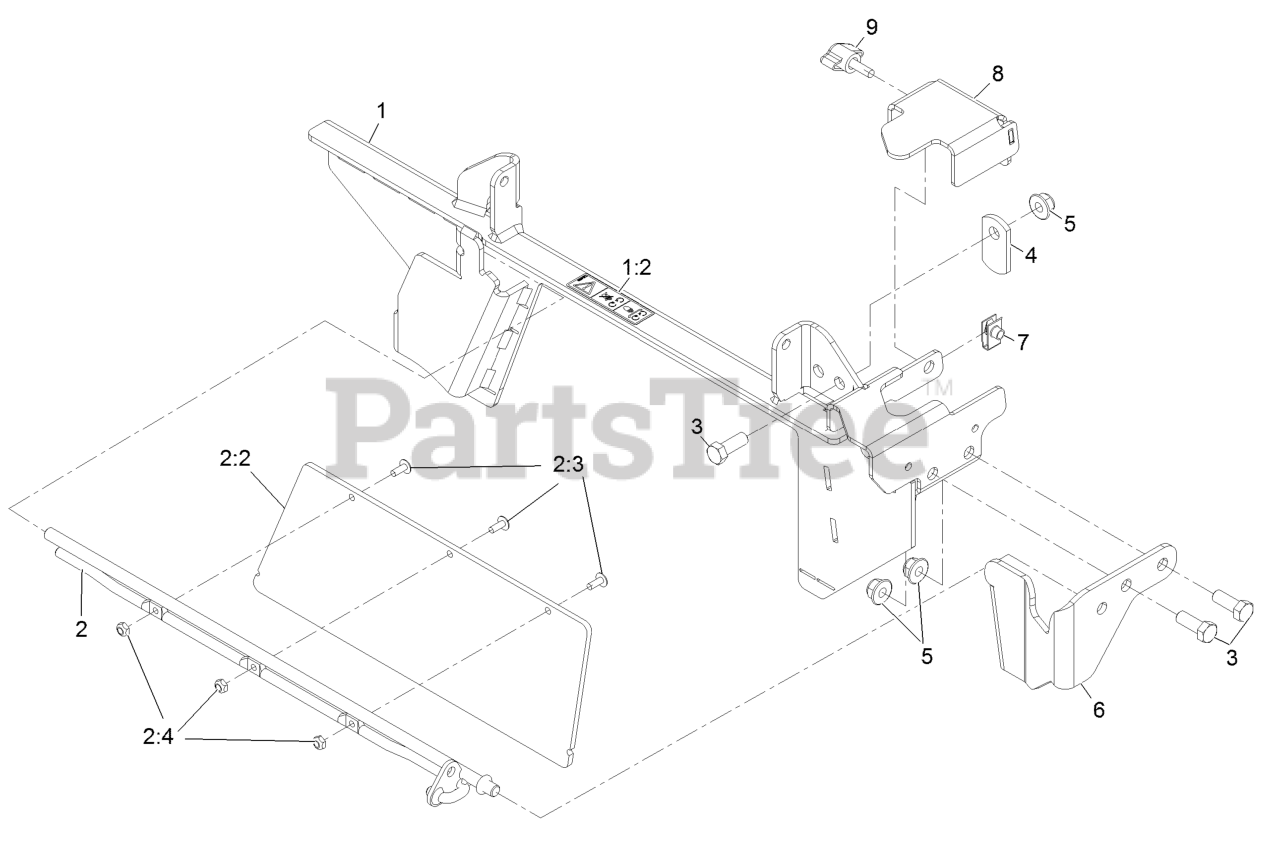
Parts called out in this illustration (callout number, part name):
1	Ocd Frame ASM W/ Decals
1:2	Decal, Cover Missing
2	Ocd Gate ASM
2:2	Gate-Ocd
2:3	Screw-Truss HD #10-24 X 1/2
2:4	Nut-Nyloc #10-24 Thin
3	Screw-HH 3/8-16 X 1
4	Latch-Catcher, Grass
5	Nut-Nyloc 3/8-16 Flg
6	Brkt,Chute Front
7	Nut-Retainer-Panel 1/4-20
8	Bracket, Cable Mount
